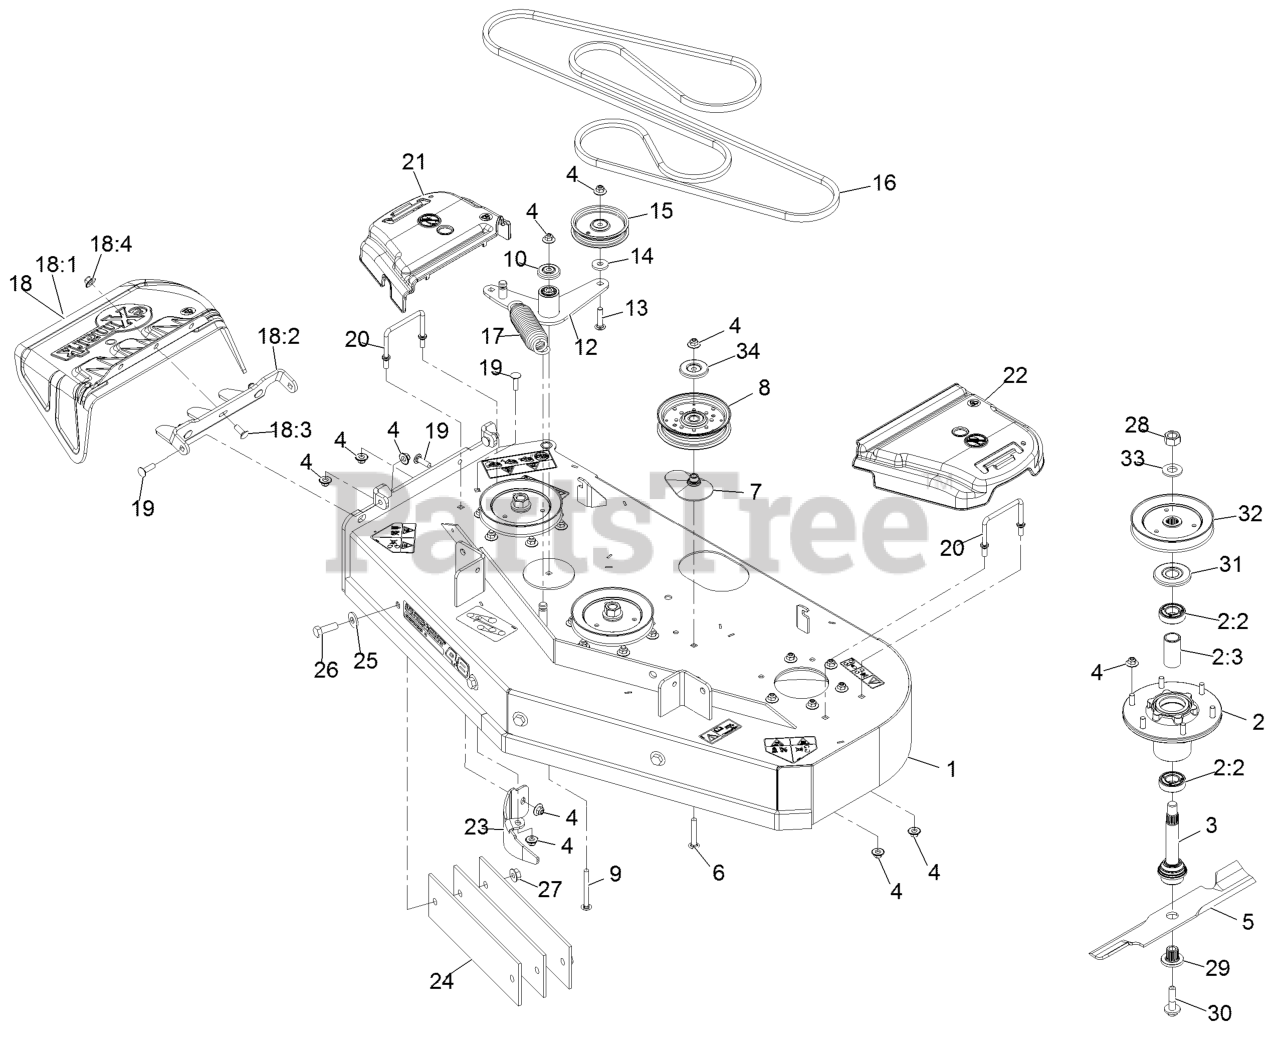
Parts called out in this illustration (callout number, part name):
1	DECK ASM-484
2	ASM-CUTTER HSG WITH BEARINGS
2:2	BEARING-BALL
2:3	SPACER-BEARING
3	ASM-SPINDLE AND SEAL
4	Nut-Nyloc 3/8-16 Flg
6	SCREW-CARR
7	SPACER-PULLEY
8	PULLEY-IDLER, FLAT
9	SCREW-CARR
10	GUARD-TOP
12	IDLER ARM ASM W/BEARINGS
13	SCREW-CARR SPECIAL
15	PULLEY-IDLER
16	V-BELT
17	SPRING-EXTENSION
18	ASM,DISCHARGE CHUTE
18:1	CHUTE,DISCHARGE
18:2	BRACKET,DISCHARGE CHUTE
18:3	SCREW-CARR
18:4	Nut-Nyloc 3/8-16 Flg
19	Bolt-Carriage 3/8-16 X 1 1/4
20	WIREFORM-COVER
21	COVER-BELT, RH
22	COVER-BELT, LH
23	BAFFLE-DOGLEG,LZS LZX VT4
24	BAR,WEIGHT
25	WASHER-SPRING
26	SCREW-HH
27	NUT-HHF
28	NUT-HEX
29	BUSHING,SPLINED
30	SCREW,SEMS 1/2-20 X 2.19
31	GUARD,BEARING TOP .989
32	SHEAVE,BLADE DRIVE 5.90
34	SHIELD-DUST
